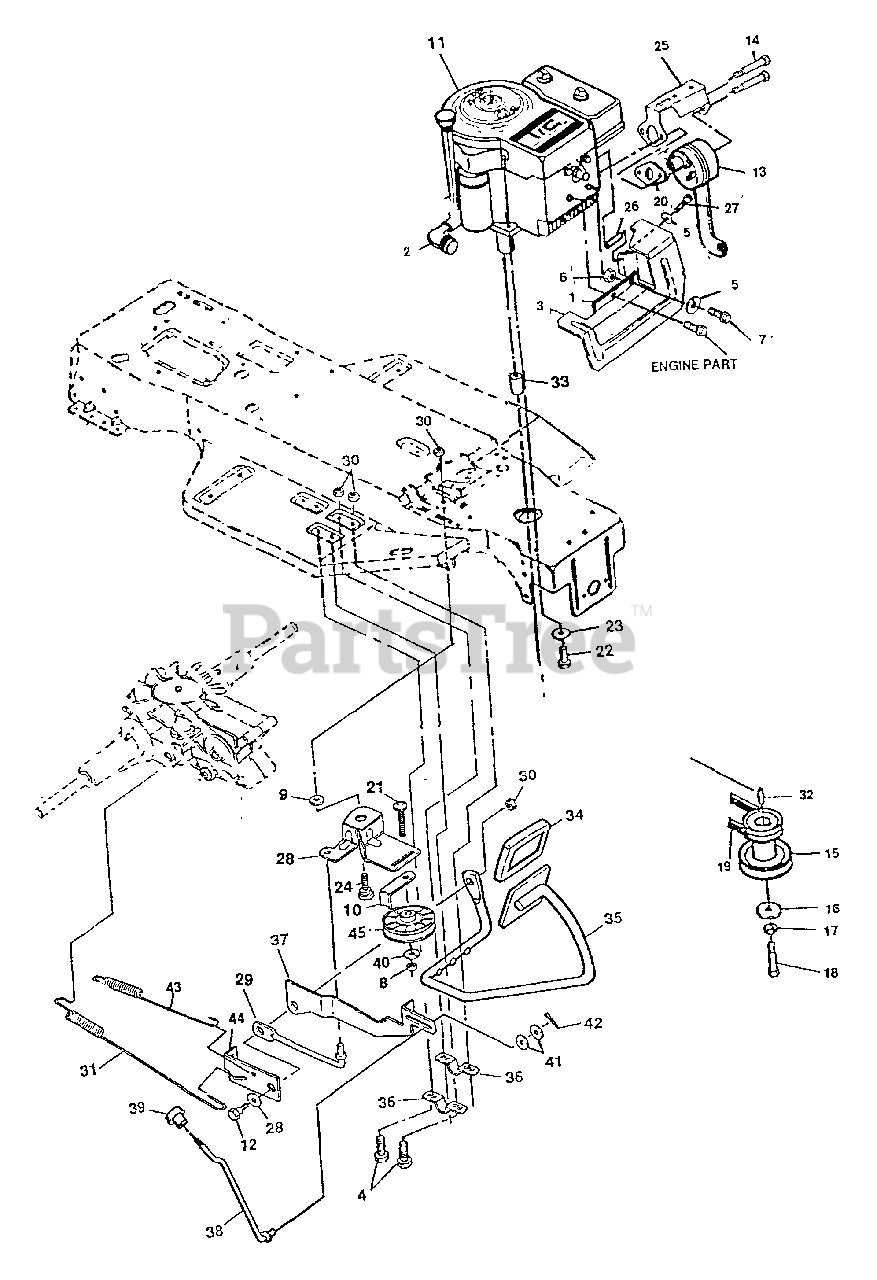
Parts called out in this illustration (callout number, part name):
2	Elbow, 90 Degree
3	Heat Shield
4	Screw, 5/16-18 x 1/2
5	Washer, Split Lock
6	Nut, 5/16 - 18
7	Screw, 14-20 x 7/8 In.
8	Nut, 3/8-16
9	Flatwasher, .333 x .87 x .119
10	Retainer, Belt
11	ENGINE
12	Bolt, Shoulder 5/16-18
13	Muffler, Round
14	Bolt, 5/16 - 18 Thd.
15	Pulley Assembly, Engine
16	Washer, Pilot
17	Washer, Split Lock 7/8
18	Screw, 716-20 x 5 In.
20	Muffler Gasket
21	Screw, 3/8-16x1-1/2 In.
22	Screw, Tap 3/8-16 x 11/4 In.
23	Washer 3/8 In.
24	Bolt, Shoulder, 5/16-18
25	Muffler Shield
26	Heat Shield Spacer
27	Screw, 1/4-20 x 3-1/2 In
28	Idler, Arm
29	Rod, Clutch
30	Nut, 5/16-18
31	Spring, Clutch
32	Key Square
34	Clutch Brake Pad
35	Clutch Brake Weld Assy.
36	Clutch Brake Arm Bracket
37	Park Brake Lever
38	Parking Brake Rod
39	Knob, Parking Brake
40	Washer, Split lock 3/8 In.
41	Flatwasher, .250 x .56 x .04
42	Cotter Pin
43	Spring, Brake
44	Bracket-Brake, Neutral
45	Idler Pulley
